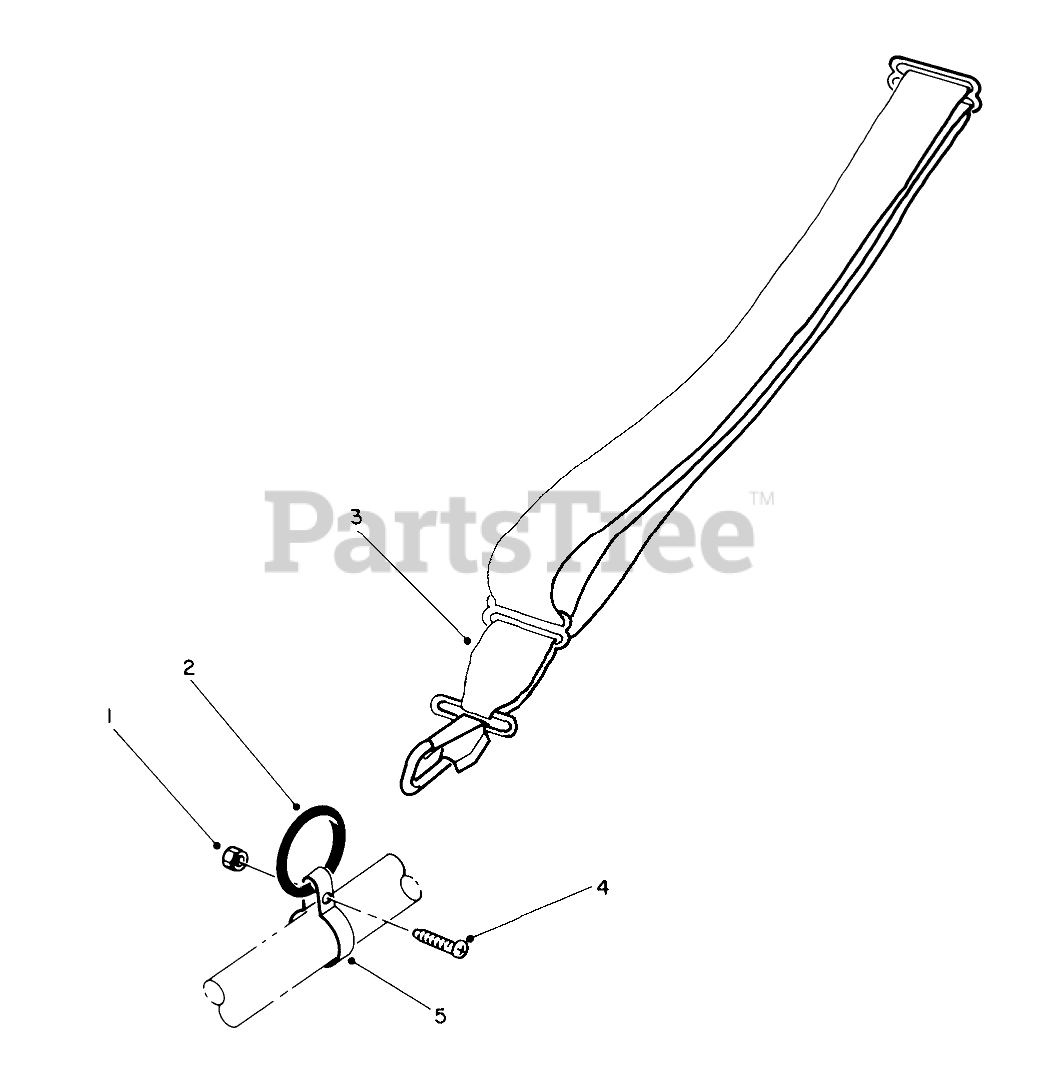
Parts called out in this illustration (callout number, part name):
1	Nut
2	Ring
3	Harness
5	Clamp
